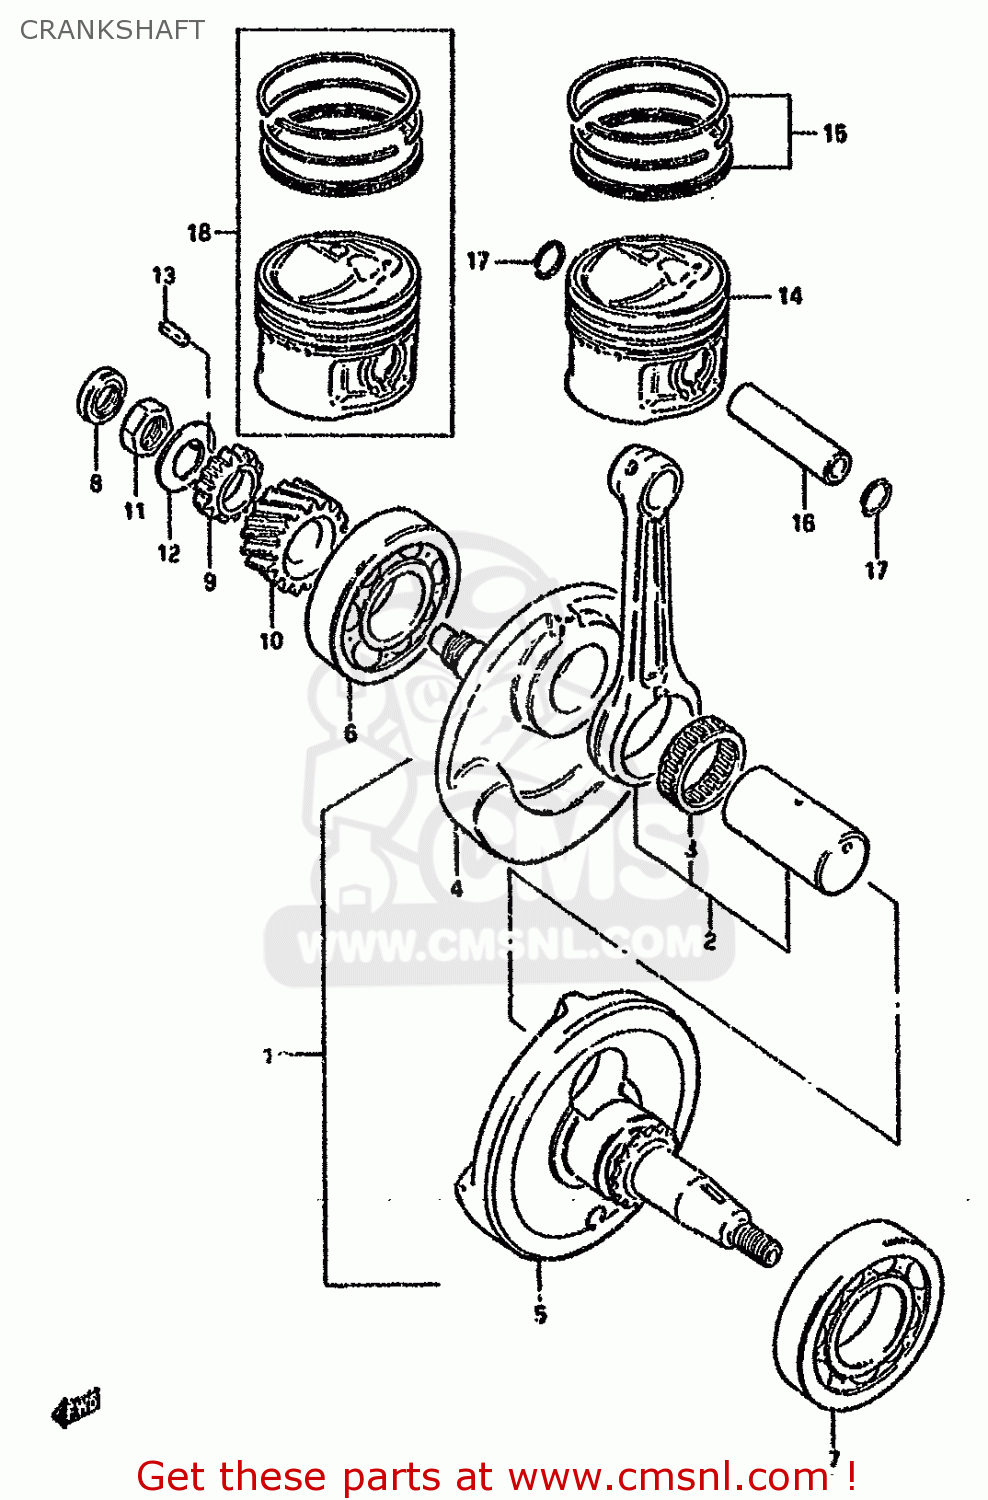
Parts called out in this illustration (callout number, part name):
1	CRANKSHAFT ASSEMBLY
2	CONNECTING ROD SET
3	BEARING
4	CRANKSHAFT,RIGHT
5	CRANKSHAFT,L
6	BEARING(28X68X18)
7	BEARING(35X72X17)
8	SEAL,OIL(12X21X7)
9	GEAR,OIL PUMP DRIVE
10	GEAR,PRIMARY DRIVE
11	NUT
12	WASHER
13	KEY
14	PISTON (STD)
15	RING SET,PISTON
16	PIN,PISTON
17	RING,SNAP 14MM
18	PISTON SET(OS:0.5)
